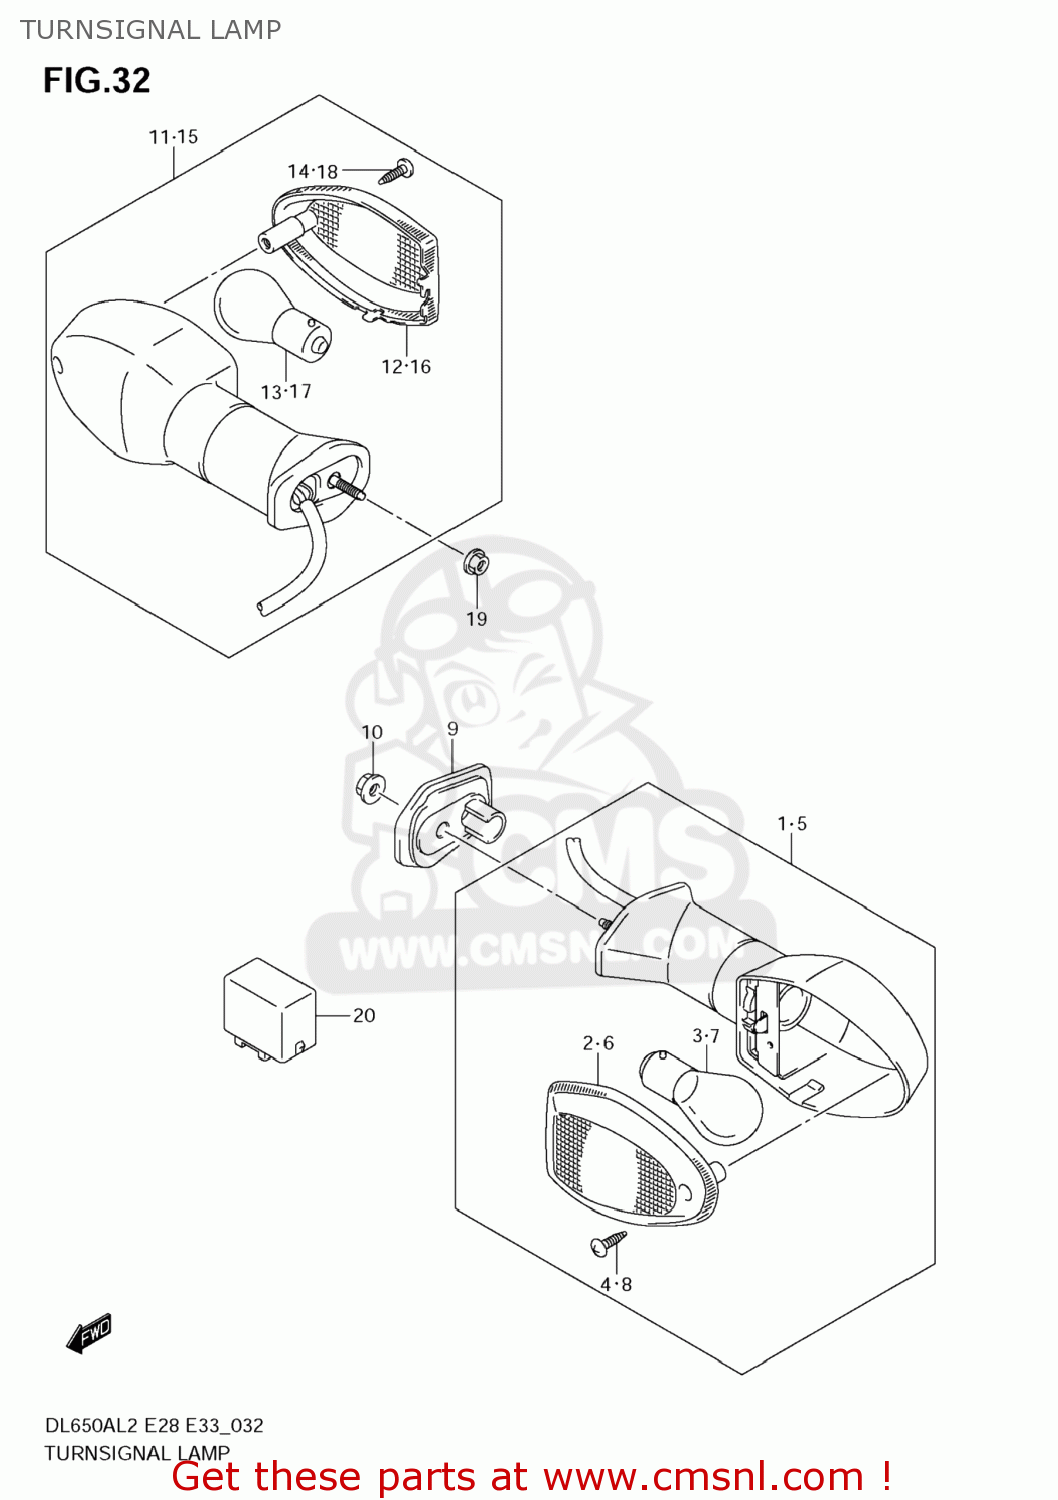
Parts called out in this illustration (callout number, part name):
1	LAMP ASSY,FRON
2	LENS,TURNSIGNA
3	BULB(12V21W)
4	SCREW
5	LAMP ASSY,FRON
6	LENS,TURNSIGNA
7	BULB(12V21W)
8	SCREW
9	PLATE,FR TURNSIGNAL
10	NUT
11	LAMP ASSY,REAR
12	LENS,TURNSIGNA
13	BULB(12V21W)
14	SCREW
15	LAMP ASSY,REAR
16	LENS,TURNSIGNA
17	BULB(12V21W)
18	SCREW
19	NUT
20	RELAY ASSY,TURNSIGNAL LAMP
